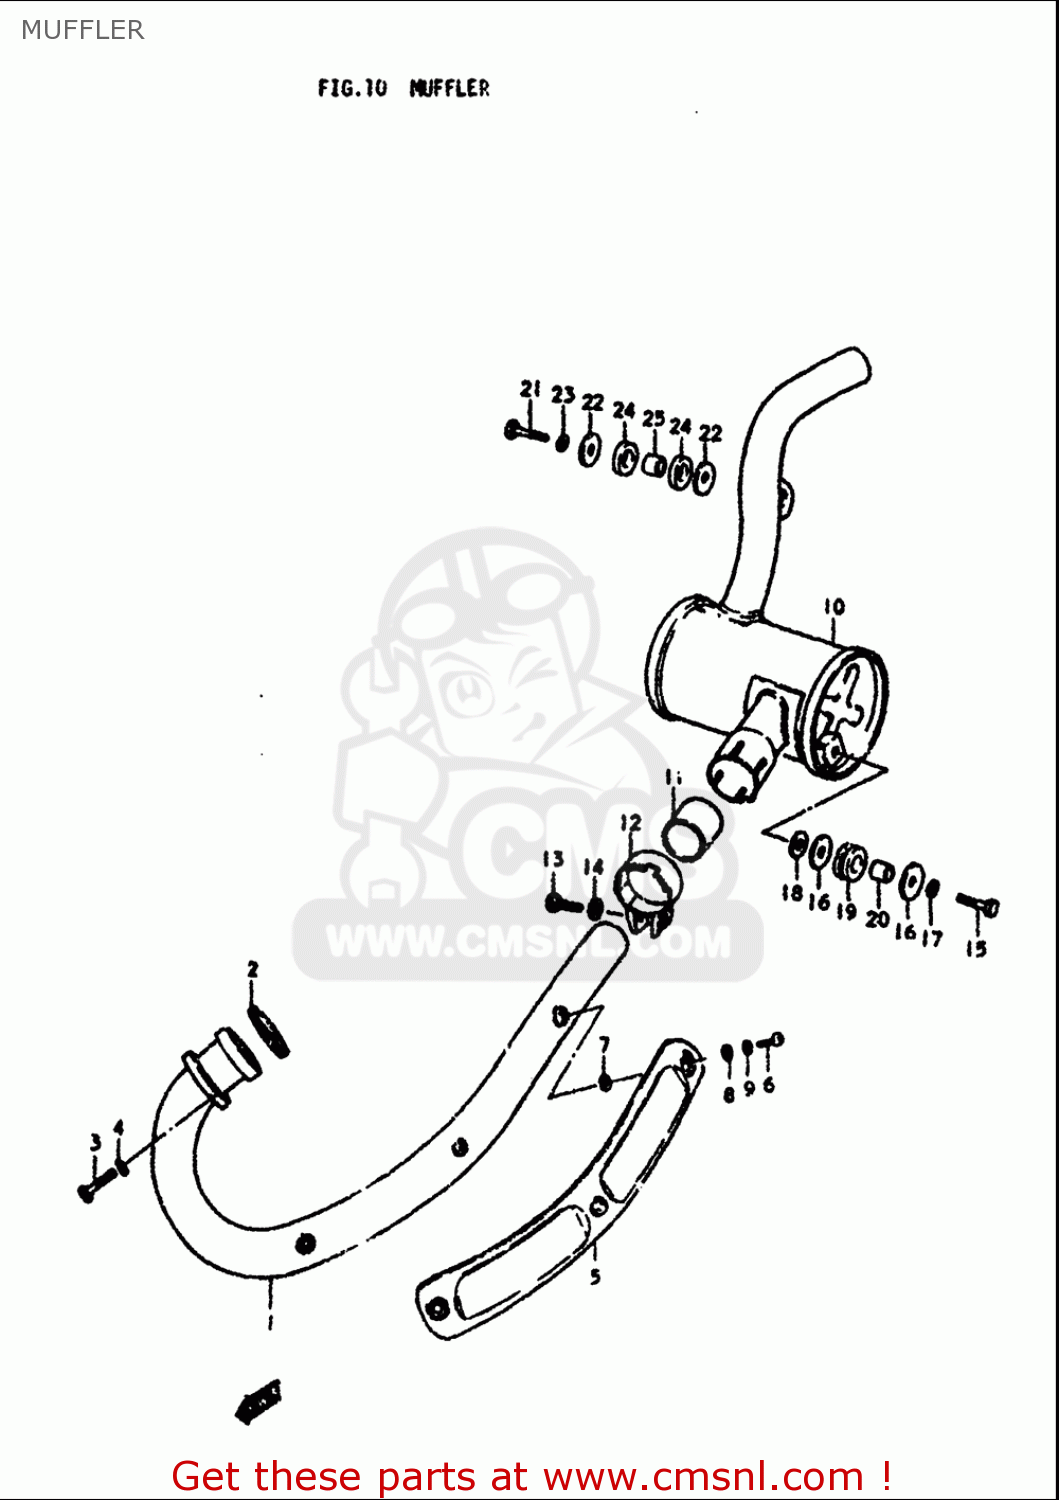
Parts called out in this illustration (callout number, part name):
1	PIPE,EXHAUST
2	GASKET,EXHAUST PIPE (NAS)
3	BOLT
4	WASHER,LOCK
5	COVER,EXHAUST PIPE
6	SCREW
7	GASKET(6.2X12X1.5) (NAS)
8	WASHER
9	WASHER,LOCK
10	MUFFLER ASSEMBLY,FIRST
11	CONNECTOR,MUFFLER
12	CLAMP,MUFFLER CONNECTOR
13	BOLT
14	WASHER
15	BOLT
16	WASHER(8.5X28X1.6)
17	WASHER,LOCK
19	CUSHION
20	SPACER (8.6X13.8X13)
21	BOLT(8X27)
22	WASHER(8.5X28X1.6)
23	WASHER,LOCK
24	CUSHION
25	SPACER (8.6X13.8X13)
